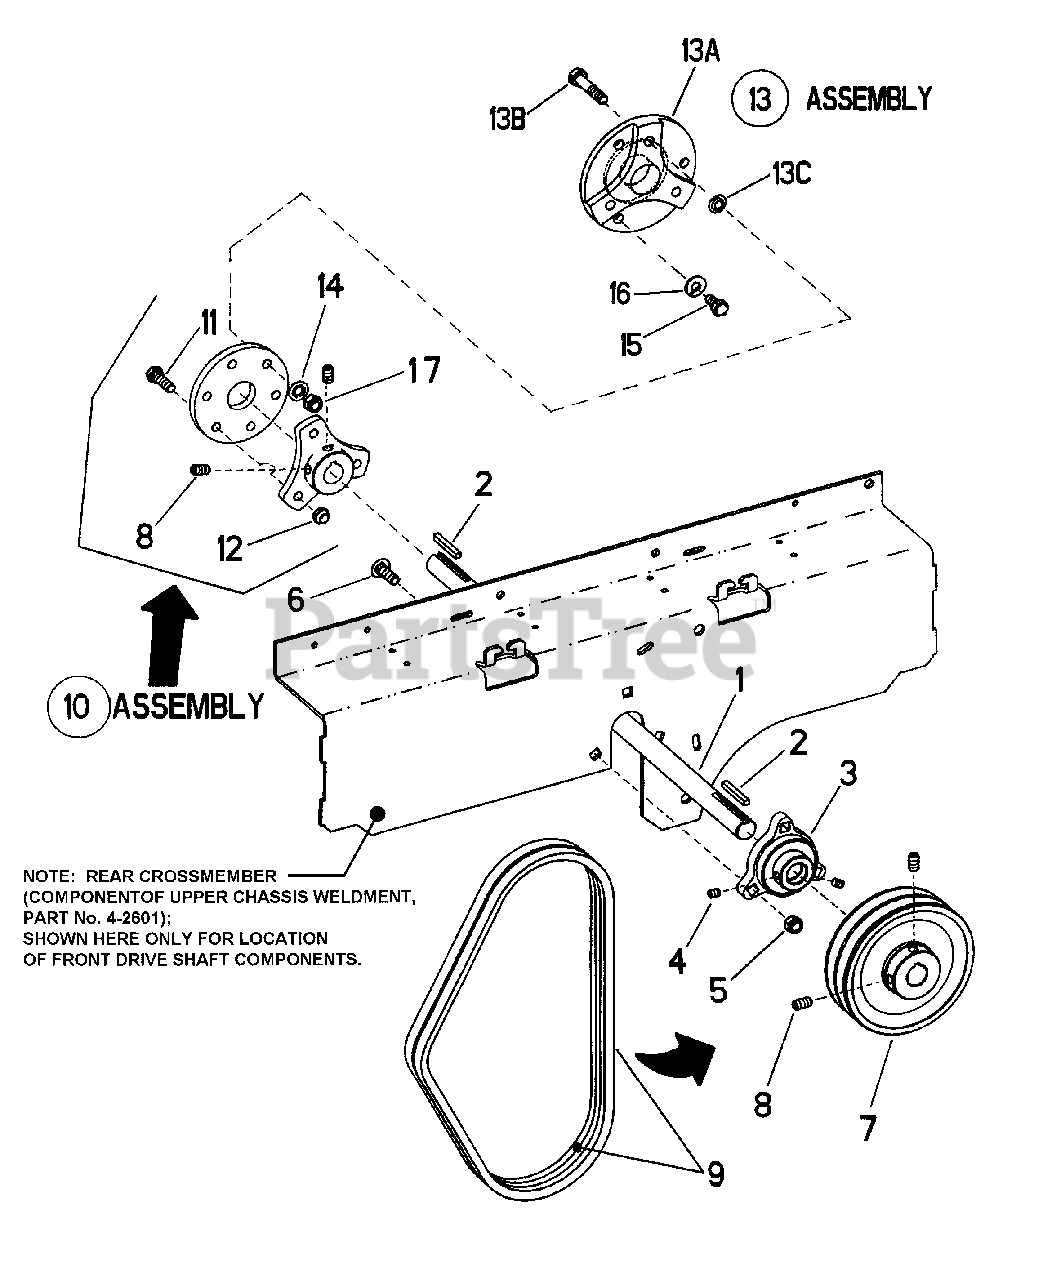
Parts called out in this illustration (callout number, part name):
1	DRIVE SHAFT, 3/4"
2	KEY, 3/16 Square x 1-1/2" Long
3	ASSEMBLY, Bearing/Lock Collar
4	SET-SCREW, 1/4-20 x 5/16" Socket-Head
5	NUT, 5/16-18 HEX NYLON LOCK
6	BOLT, 5/16-18 x 1" Round Head Square Neck, Grade 5
7	PULLEY, Cast Iron Dual V, 49.5 Effective O.D.
8	SET-SCREW, 5/16-18 x 5/8", Socket-Head
9	BELT, 36-1/2" (Upper Drive Shaft to Hydro Pump)
10	FLEX COUPLING, 3/4" Shaft
11	SCREW, 5/16-24 x 1" Hex Head Cap, Grade 5
12	NUT, 5/16-24 Hex Lock
13	ASSEMBLY, Coupling Adapter
13A	ADAPTER, Coupling
13B	SCREW, 5/16-18 x 1-1/2" Hex Head Cap, Grade 5
13C	RETAINER, 5/16 Bolt
14	WASHER, 5/16 Double Beaded
15	SCREW, M8-1.25 x 20 Hex Head Cap
16	WASHER, .32 I.D. Split Lock
17	NUT, 5/16-18 Hex Top Lock, Grade B
